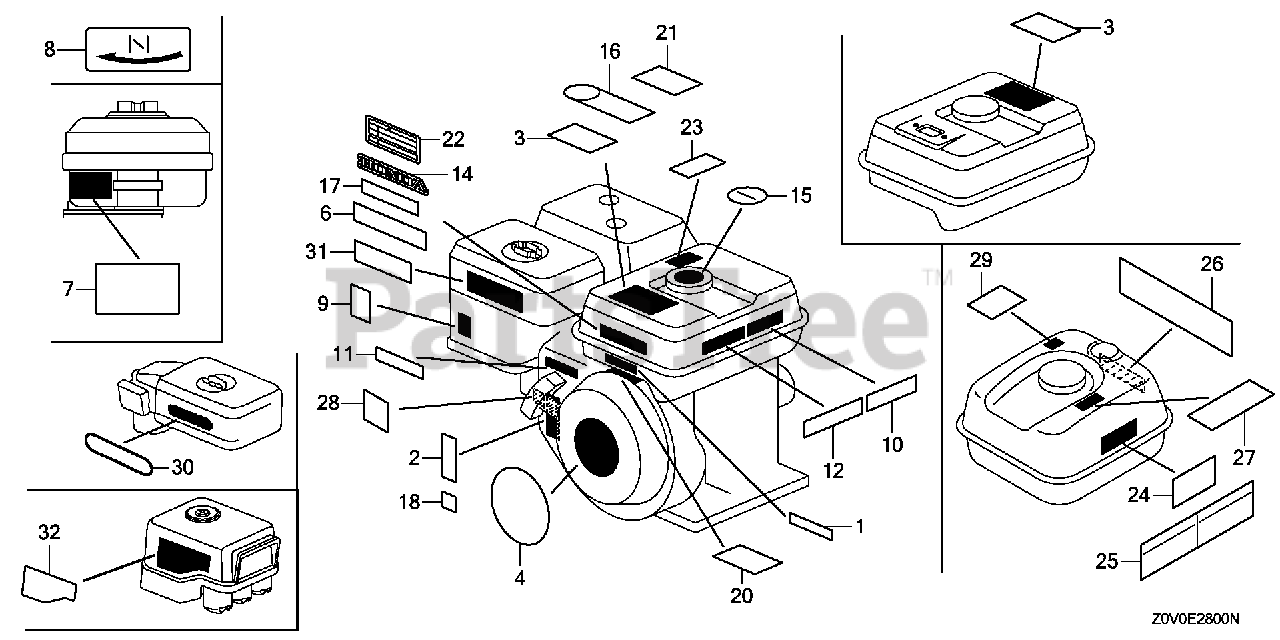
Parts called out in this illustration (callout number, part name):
4	EMBLEM (GX200)
9	MARK, CHOKE
11	MARK, THROTTLE INDICATION
18	LABEL, WARNING (NOT CERTIFIED FOR SALE)
24	MARK, OPERATOR CAUTION (ENGLISH)(MADE IN THAI)
29	MARK, EX. CAUTION (ENGLISH)
